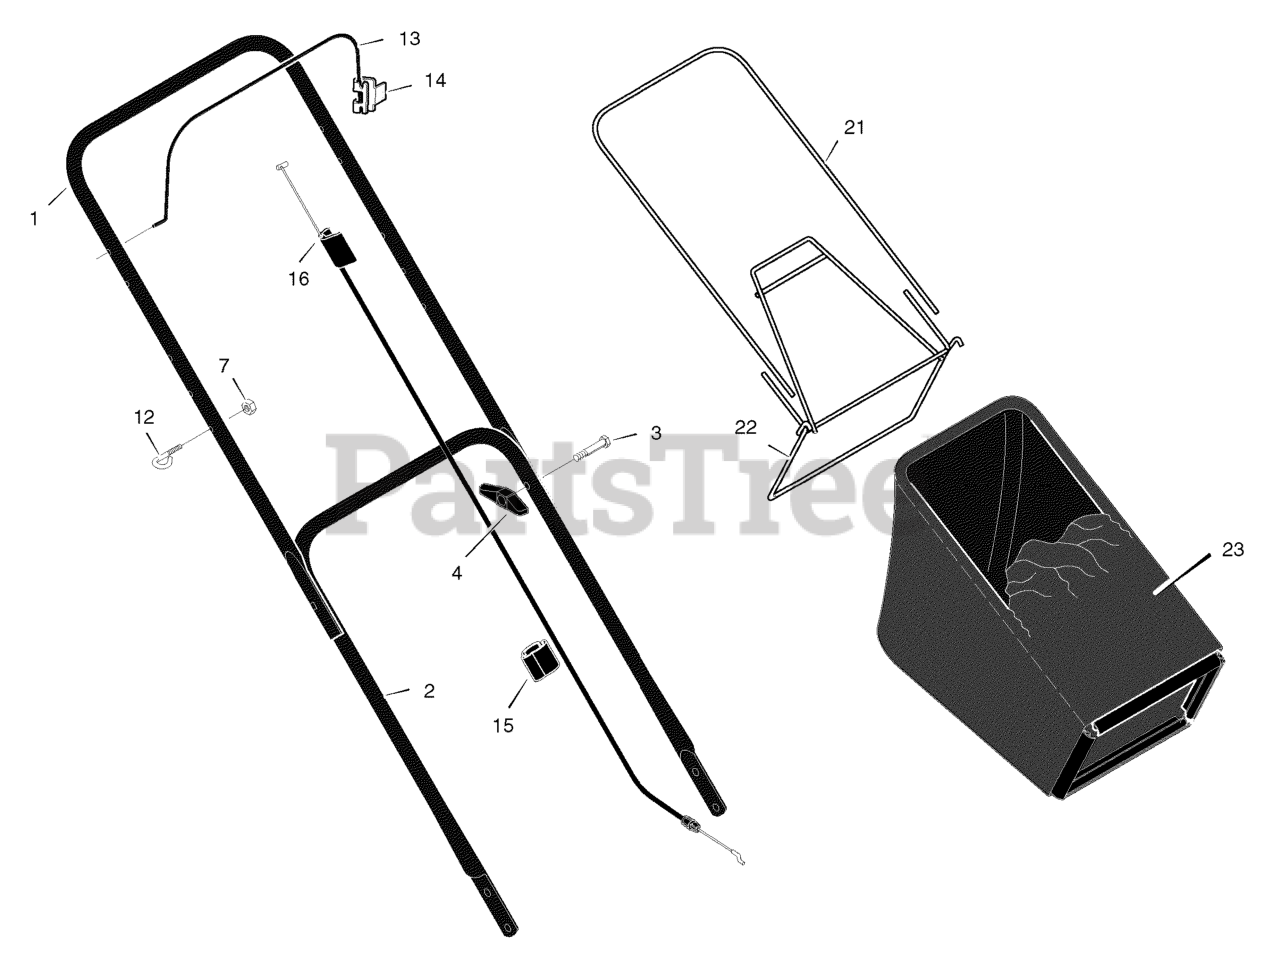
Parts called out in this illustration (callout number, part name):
1	Handle, Upper (Black)
2	Handle, Lower (Black)
4	Knob, Plastic
7	Locknut
12	Guide, Rope
13	Engine Stop Lever
14	Bracket, Stop Lever
15	Fastener, Cable
16	Engine Stop Cable
21	Frame, Top
22	Frame Assembly
23	Bag, Cloth -Black
